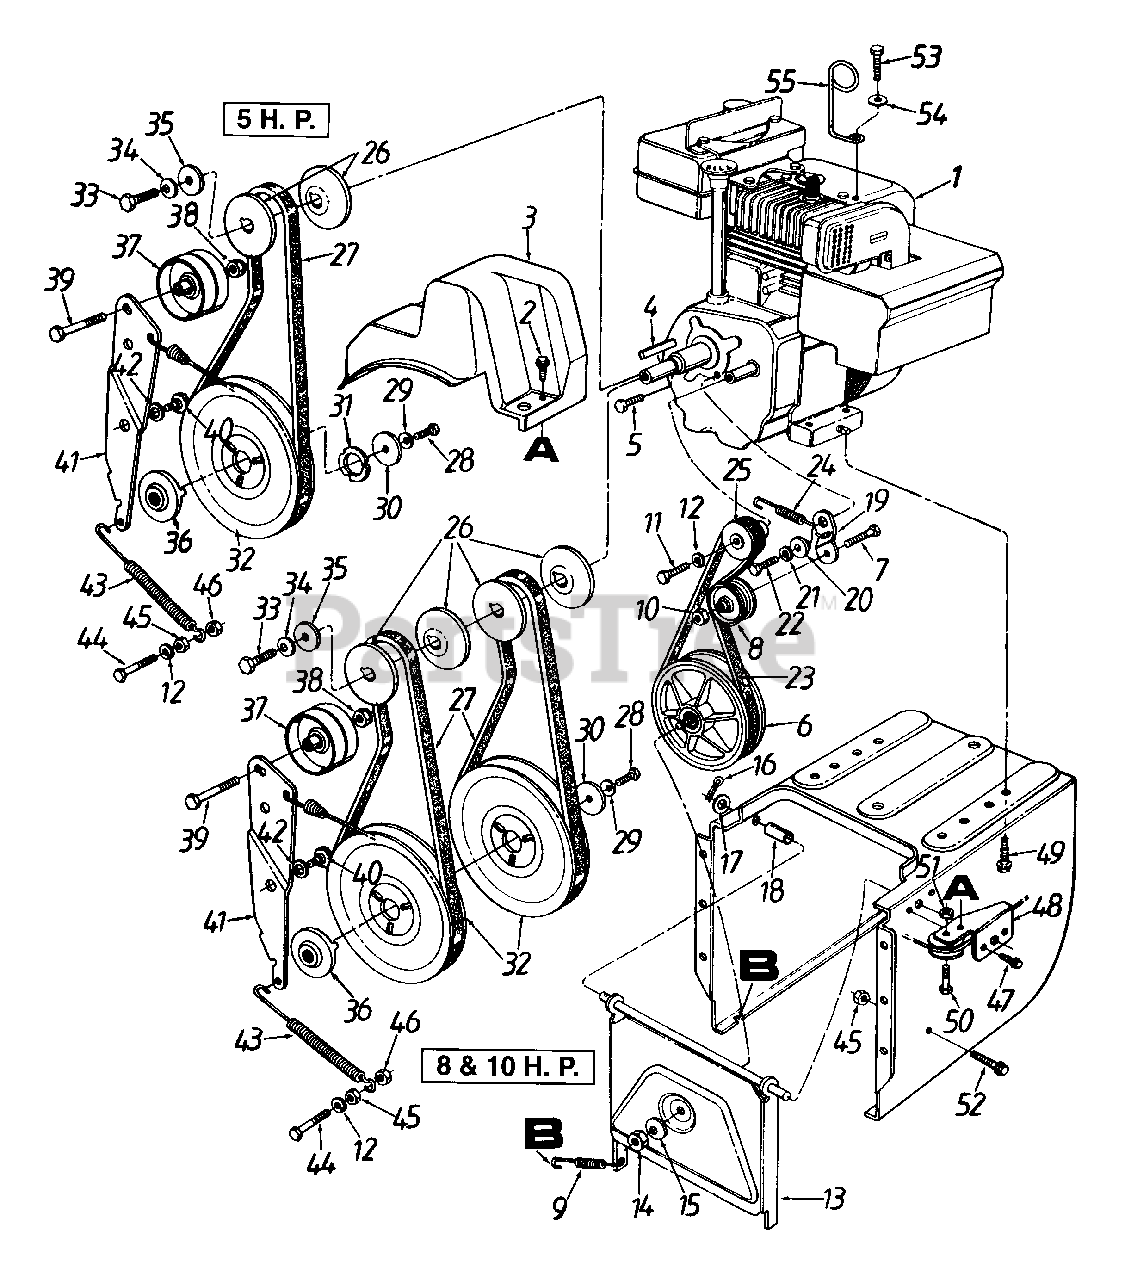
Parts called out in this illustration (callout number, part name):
1	Engine
2	Hex Wash. Hd. TT-Tap Scr. 1/4-20 x .5" Lg.
3	Belt Cover
4	Sq. - Key 3/16 x 1.5" Lg. (646F & 666H)
4	Sq. - Key 3/16 x .75" Lg. (616E)
5	Hex Patch Bolt 5/16-24 x 1" Lg. (Gr. 5)
6	Friction Wheel Disc Ass'y.
7	Hex Bolt 3/8-16 x 1.25" Lg.
8	Fl-Idler 2.12" O.D.
9	Ext. Spring 2.5" Lg.
10	Hex Top L-Nut 3/8-16 Thd.
11	Hex Bolt 1/4-28 x .5" Lg.
12	L-Wash. 1/4" I.D."
13	Friction Wheel Support Brkt. Ass'y.
14	Hex Jam Nut 3/8-24 Thd.
15	Bell - Wash. .38" I.D. x .88" O.D.
16	Cotter Pin 1/8" x .75" Lg.
17	Fl-Wash. .531" I.D. x .93" O.D.
18	Spacer .508" I.D. x .75" O.D.
22	Hex Bolt 5/16-24 x 1" Lg. (616E)
22	Hex Wash. Hd. Tap Scr. 5/16-18 x .62" Lg. (646F & 666H)
23	V Belt (616E)
23	V Belt (646F & 666H)
24	Extension Spring (616E)
24	Extension Spring (646F & 666H)
25	2" Dia. Pulley
26	3/8 "V" - Pulley Half
27	V - Belt (616E)
28	Hex Cap L-Bolt 5/16-24 x .75" Lg.
29	Bell - Wash .345" I.D. x .88" O.D.
30	Fl-Wash .34" I.D. x 1.5" O.D.
31	Brg. Retaining Washer (616E Only)
32	Auger Pulley
33	Hex Bolt 3/8-24 x .88" Lg.
34	Bell - Wash. .39" I.D. x 1.13" O.D.
35	Fl-Wash .406" I.D. x 1.25" O.D.
36	Adapter Pulley
37	Fl-Idler 2.75" O.D.
38	Hex Ins. L-Nut 3/8-24 Thd.
39	Hex Bolt 3/8-24 x 1.5" Lg. (Gr 5)
40	Shld Bolt .625" Dia. x .170" Lg.
41	Auger Idler Brkt.
42	Wave Wash .66" I.D. x .88"
43	Ext. Spring 3.6" Lg
44	Hex Bolt 1/4-20 x .75" Lg (Gr 5)
45	Hex Nut 1/4-20 Thd.
46	Hex L-Nut 1/4-20 Thd
47	Torx Mach. AB-Tap Scr 1/4 x .62" Lg
48	Front Support Brkt Guide
49	Hex L-Wash TT-Tap Scr 3/8-16 x 1.25" Lg
50	Shld. Bolt 5/16" Dia x 35" Lg
51	Hex Jam Nut 1/4-20 Thd
52	Hex Wash Hd TT-Tap Scr. 1/4-20 x 1" Lg.
53	Hex Wash Hd Tap Scr 5/16-18 x 1" Lg. (646F & 666H)
54	Fl-Wash. .349" I.D. x .879" O.D. (646F & 666H)
55	Cable Control Wire (646F & 666H)
